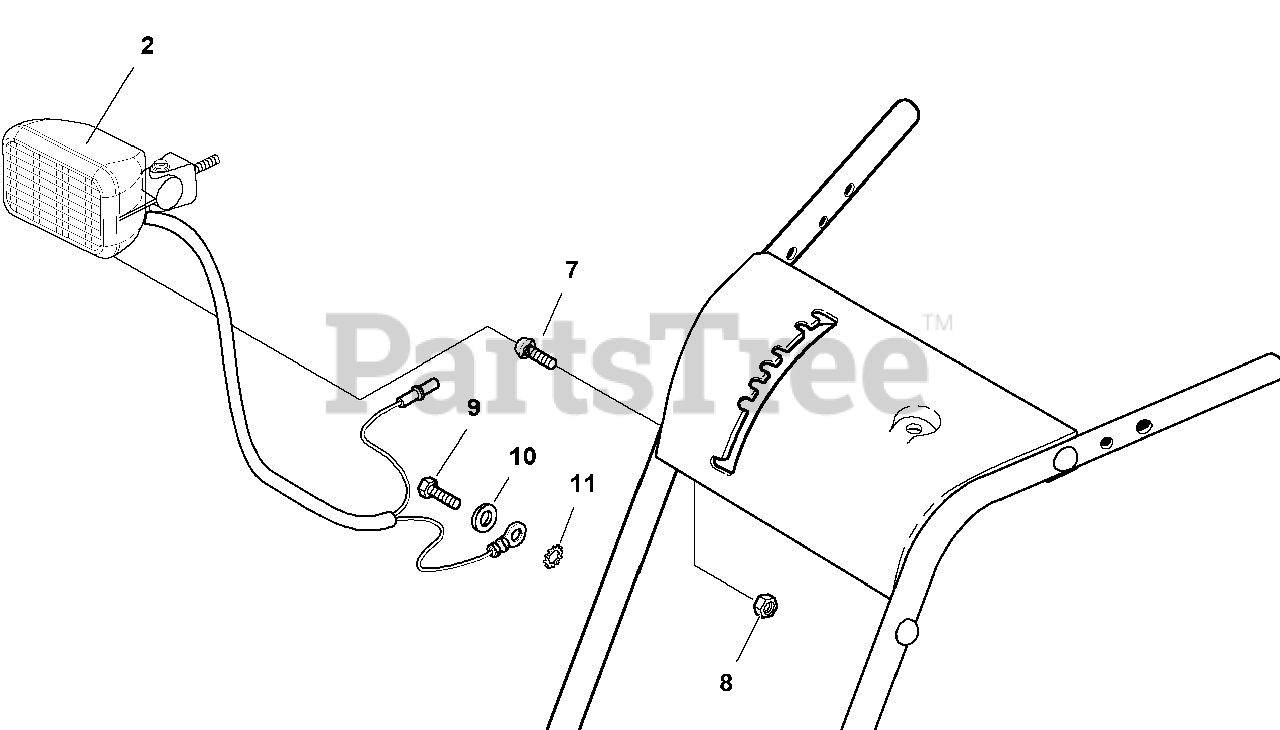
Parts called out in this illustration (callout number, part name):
2	LIGHT & COVER ASSEMBLY
3	CAPSCREW, Hex Hd., 1/4-20 x 1/2
4	LOCK WASHER, External Tooth, 1/4
5	CAPSCREW, Hex Hd. Taptite, 3/8-16 x 3/4
9	LIGHT & COVER ASSEMBLY
10	CAPSCREW, HEX HD., 5/16-18 x 1
11	WASHER
12	LOCK WASHER, Internal Tooth
